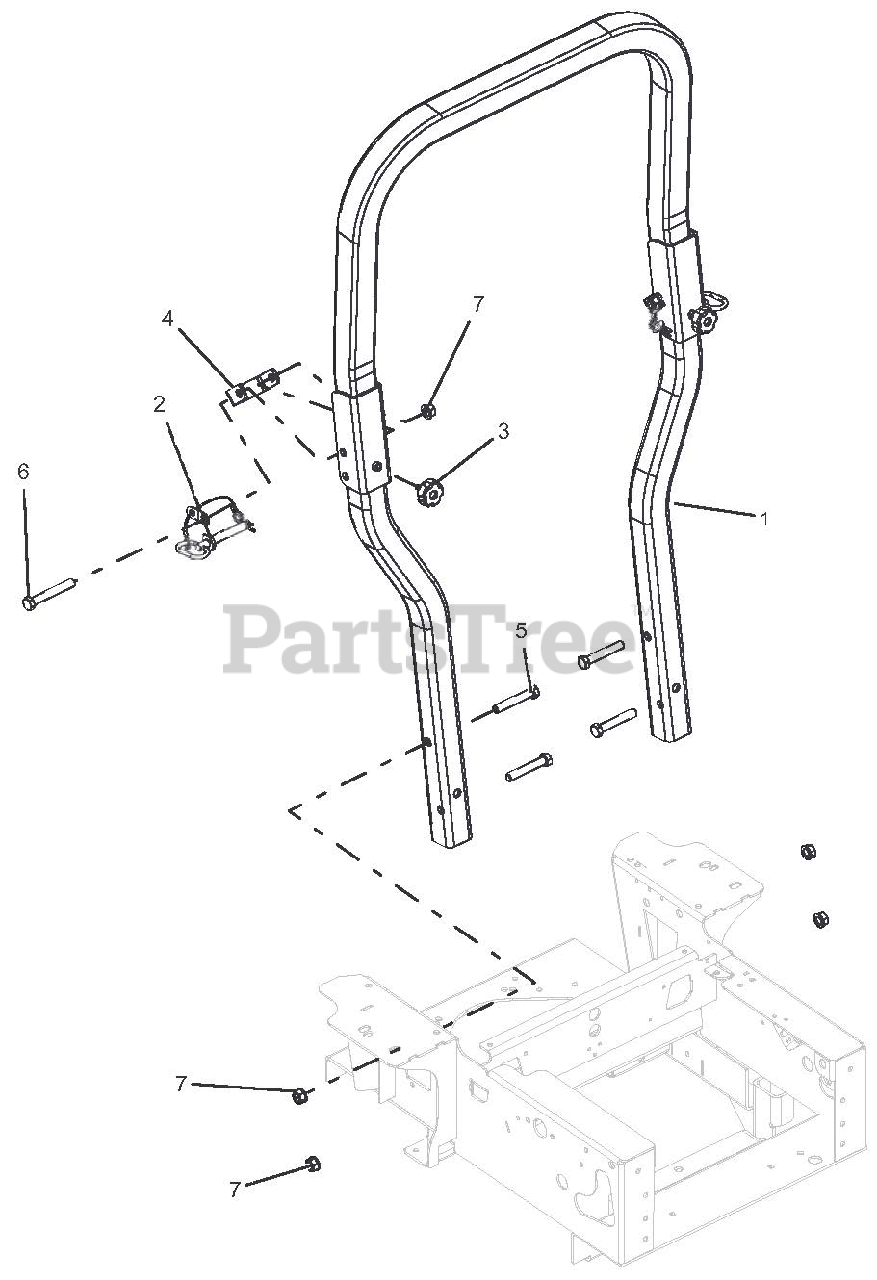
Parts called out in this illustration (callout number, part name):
1	ROPS, PT/TP100 REPLACEMENT
2	ASSY, ROPS PIN/LANYARD
3	KNOB, ROUND 5/16-18 X .750
4	BRKT, ROPS STOP, PRO-TURN YZ
5	BLT-HEX .50-13 X 3.00 GR5 YWZC
6	BLT-HEX .50-13 X 3.50 GR5 YWZC
7	NUT, LK-TOP-FLG .50-13 YWZC
